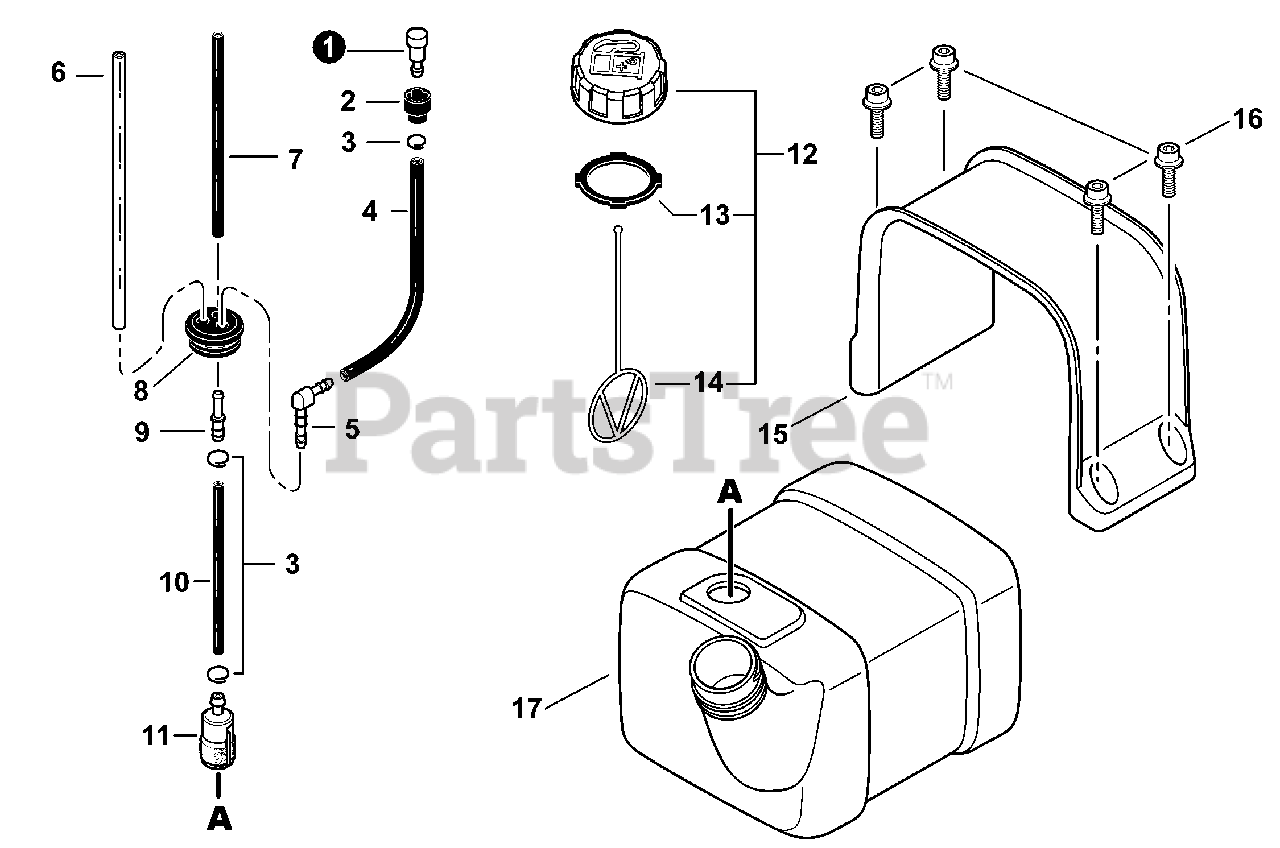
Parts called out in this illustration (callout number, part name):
1	VENT ASSY
2	HOLDER, VENT
3	CLIP 6.5MM
4	PIPE, VENT 3×6×145mm
5	CONNECTOR, PIPE 5.4
6	PIPE, FUEL RETURN 3×6×145
7	PIPE, FUEL 3×5×110
8	GROMMET, FUEL
9	CONNECTOR, PIPE 5×3.5
10	PIPE, FUEL 3×6×120
11	FILTER, FUEL
12	CAP ASSY, FUEL
13	GASKET, FUEL CAP
14	CONNECTOR, CAP L= 100mm
15	BRACKET, FUEL TANK
16	BOLT 5×16
17	TANK, FUEL
